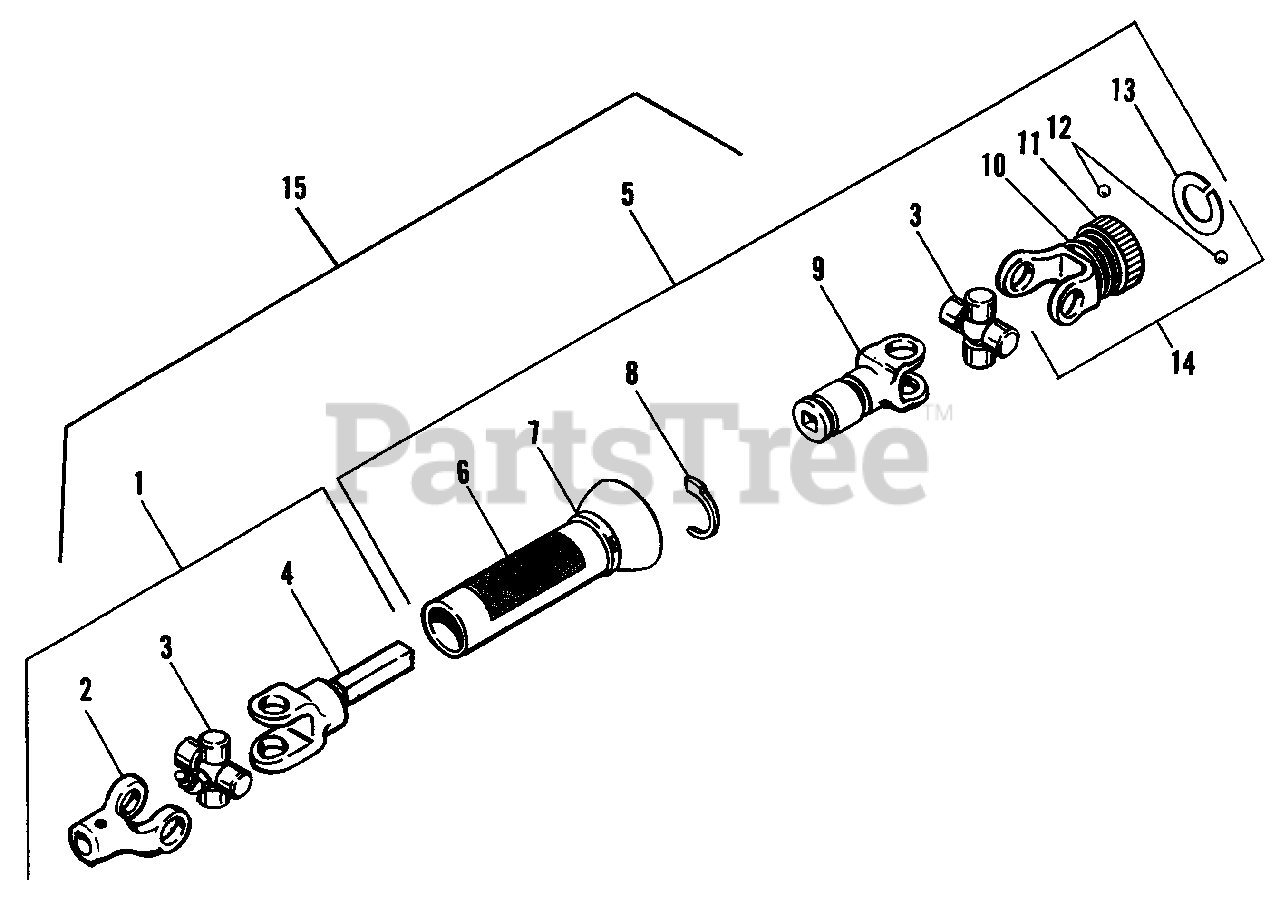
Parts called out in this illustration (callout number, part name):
1	YOKE & SHAFT ASSY.
3	JOURNAL ASSY.
4	YOKE & SHAFT
5	SLIP YOKE ASSY., w/Shield
6	DECAL, Shield
9	SLIP YOKE ASSY.
14	YOKE ASSY.
15	COMPLETE DRIVE SHAFT ASSY.
